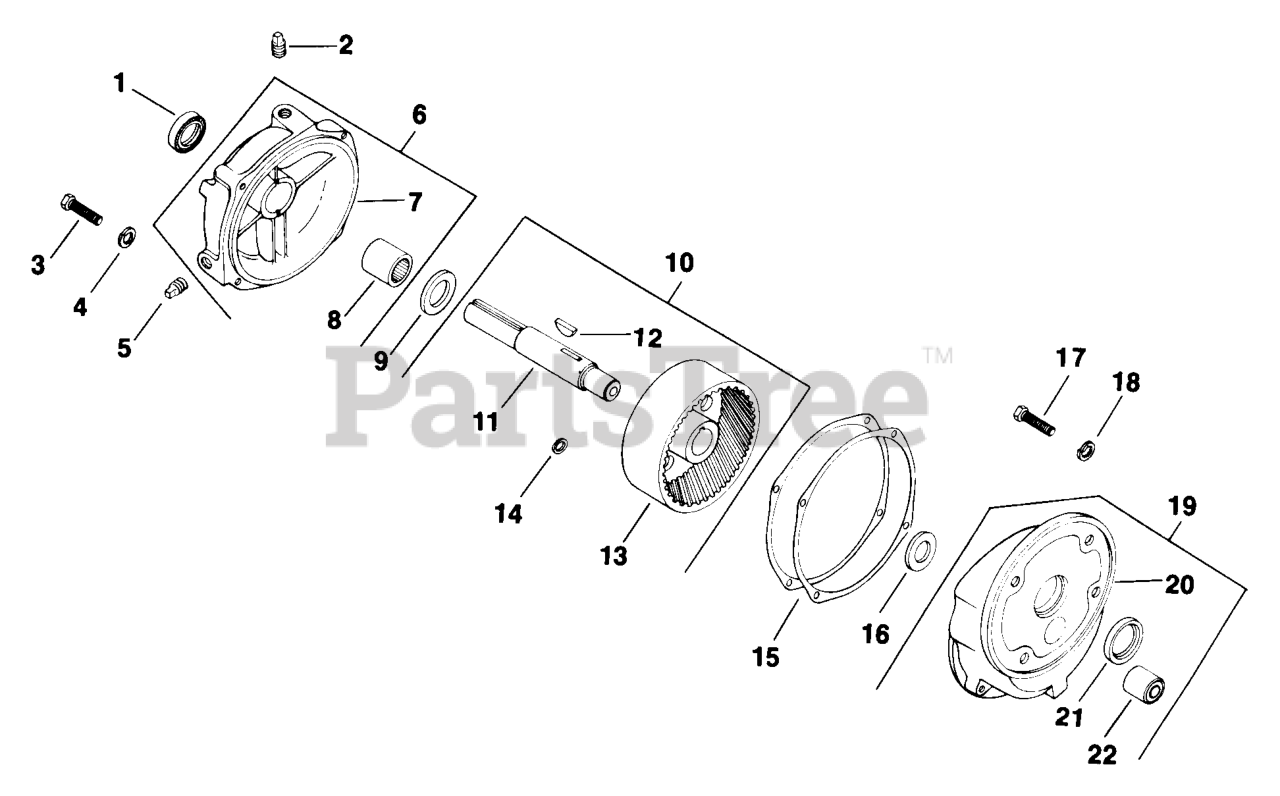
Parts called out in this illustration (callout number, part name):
1	SEAL - DISCONTINUED
3	SCREW,CAP HD 5/16-18x2"
4	WASHER, SPRING LOCK 5/16"
5	PLUG,PIPE 1/4 NPTF SQUARE HD USE 25 139 53-S
6	COVER - USE 12 081 06
7	COVER - DISCONTINUED
8	BEARING - DISCONTINUED
10	RED GEAR - DISCONTINUED
11	SHAFT - DISCONTINUED
12	KEY, 3/16" X 1"
13	GEAR - (#DSC)
17	SCREW - DISCONTINUED
18	WASHER, SPRING LOCK 3/8"
19	HOUSING - DISCONTINUED
20	HOUSING - (#DSC)
21	SEAL, FRONT OIL
